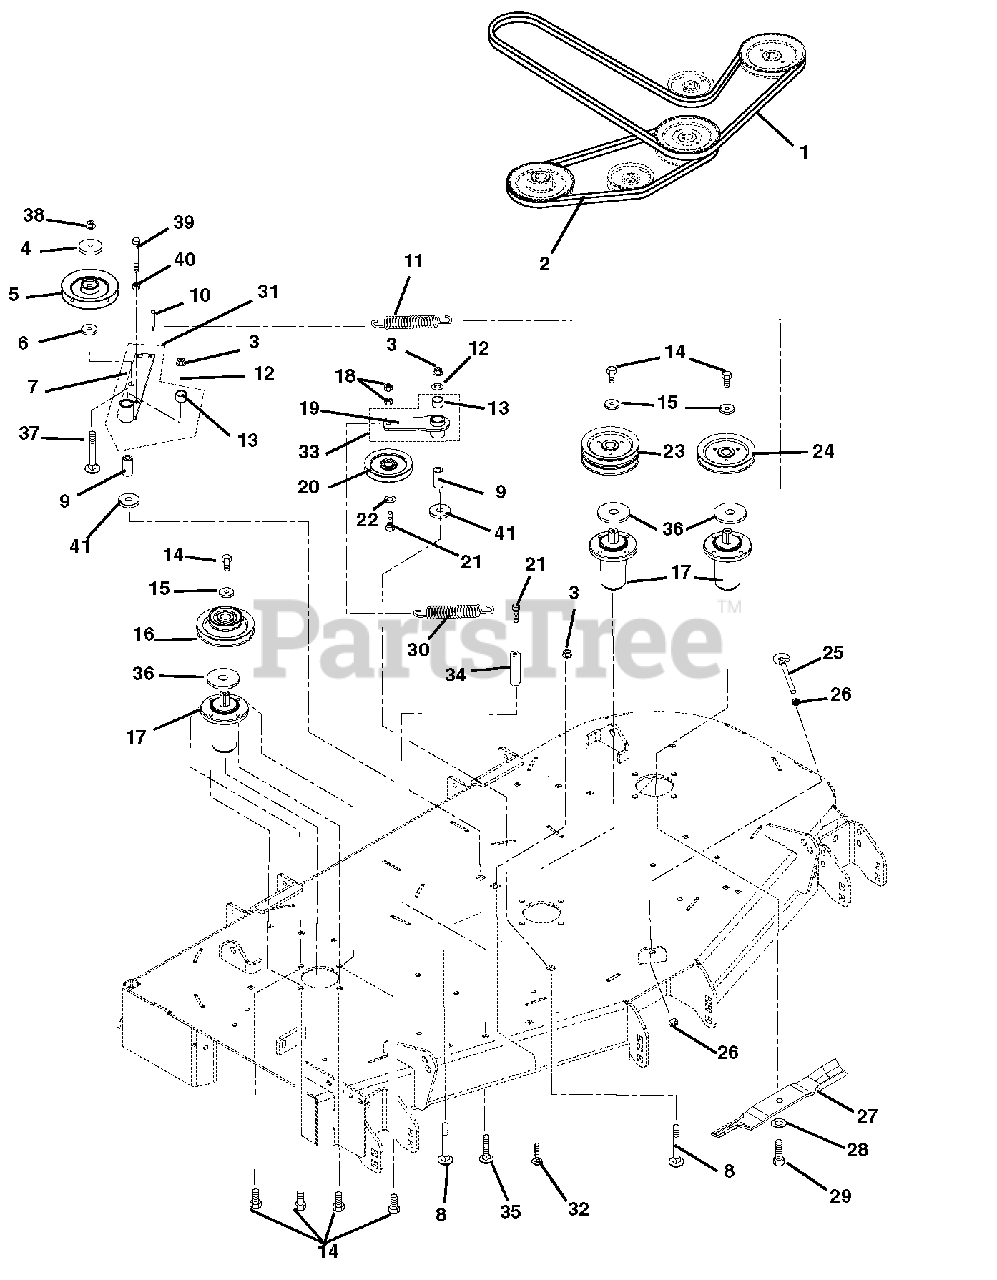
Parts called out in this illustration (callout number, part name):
1	Belt, 130" Long, PTO Drive Hex
2	V-Belt, 63" Long Cog B-Section
3	Nut, .50-13 Nyloc Flange
4	Cap, Idler Bearing Sealing
5	Sheave, .50"ID x 6.00"OD V-Idler
6	Bushing, Spacer .502 x .997 x .50
7	Idler, Pivot Arm
8	Bolt, Round Head Square Neck .50-13 x 3.50
9	Bushing, Spacer .505/.500 x .999/.996 x 2.05/2.03
10	Bolt, Shoulder .38-16 x .30 Hex
11	Spring, Extension)
12	Washer, Flat Steel .563 x 1.38 x .109
13	Bushing, 1.00 x 1.125 x 1.936
14	Bolt, Hex .38-16 x 1.00
15	Washer, Flat Steel .406 x 1.50 x .245
16	Sheave, Double, 1" ID x 6.75" x 4.25" OD
17	Spindle Assembly
18	Nut, Locking-Center .38-16
19	Idler, Pivot Arm
20	Assembly, V-Idler 5.00 O.D.
21	Bolt, Hex .38-16 x 2.25
22	Washer, Flat Steel .406 x .812 x .065
23	Pulley, Double 1" ID x 6.75" OD
24	Pulley, V-1" ID x 6.75" OD
25	Bolt, .38-16 x 5.50 .62 Diameter Eye
26	Nut, Hex, Jam .375-16
27	Blade, Mower (20.50")
28	Washer, Bellville .63 x 1.625 x.14
29	Bolt, Hex .62-18 x 1.75 Grade 8
30	Spring, Extension
31	Assembly, PTO Idler Pivot Arm (Includes item # 7 and item # 13)
32	Bolt, Round Head Square Neck .50-13 x 1.5, Full Thread, Grade 5
33	Assembly, Idler Pivot Arm (Includes item # 13 and item # 19 )
34	Nut, Coupling .375-16 x 1.75
35	Bolt, Round Head Square Neck .38-16 x 1.00
36	Retainer, Grease
37	Bolt, Round Head Square Neck .50-13 x 3.00 Grade 5
38	Nut, Locking Center .50-13
39	Bolt, Hex .38-16 x 2.75 Grade 5
40	Nut, Hex .38-16
41	Washer, Flat .640 x1.75 x.25
